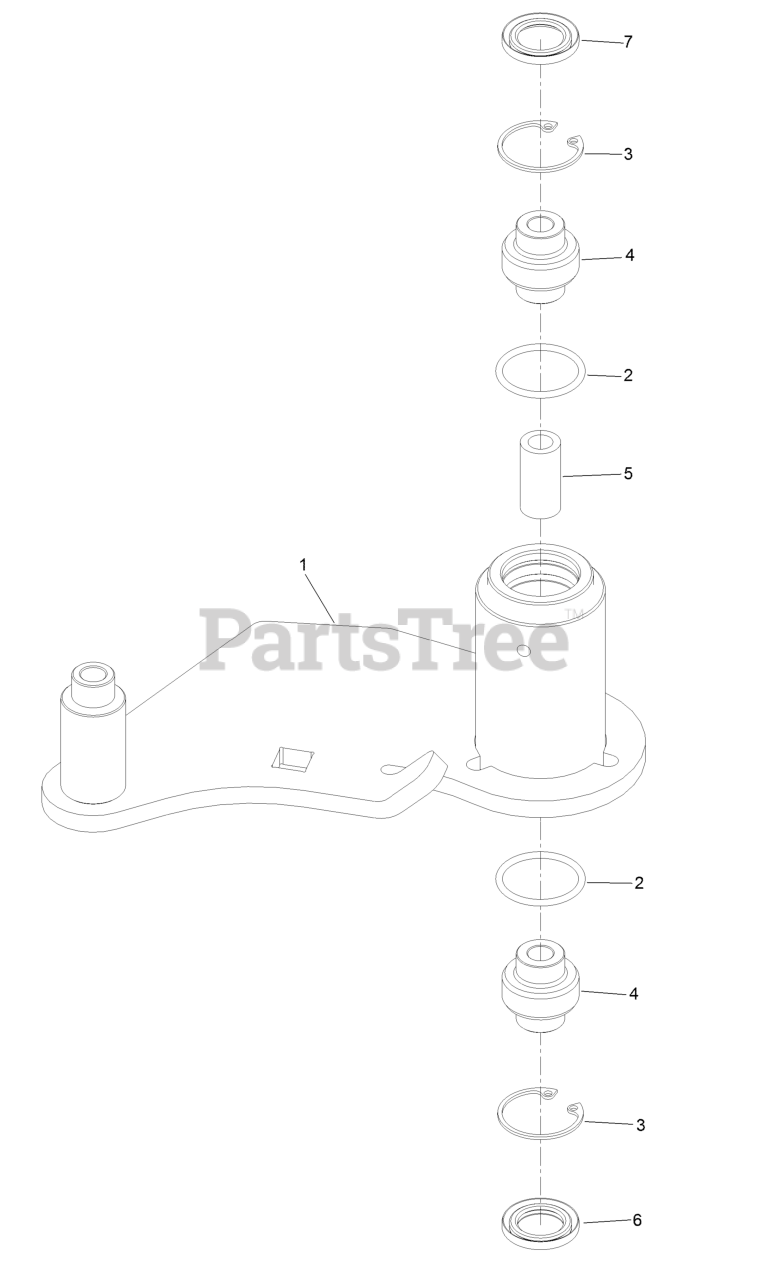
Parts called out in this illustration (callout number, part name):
1	Idler-Deck
3	Ring-Snap
4	Bearing-Spherical
6	Seal-Lip, Double
7	Seal-Lip, Single
